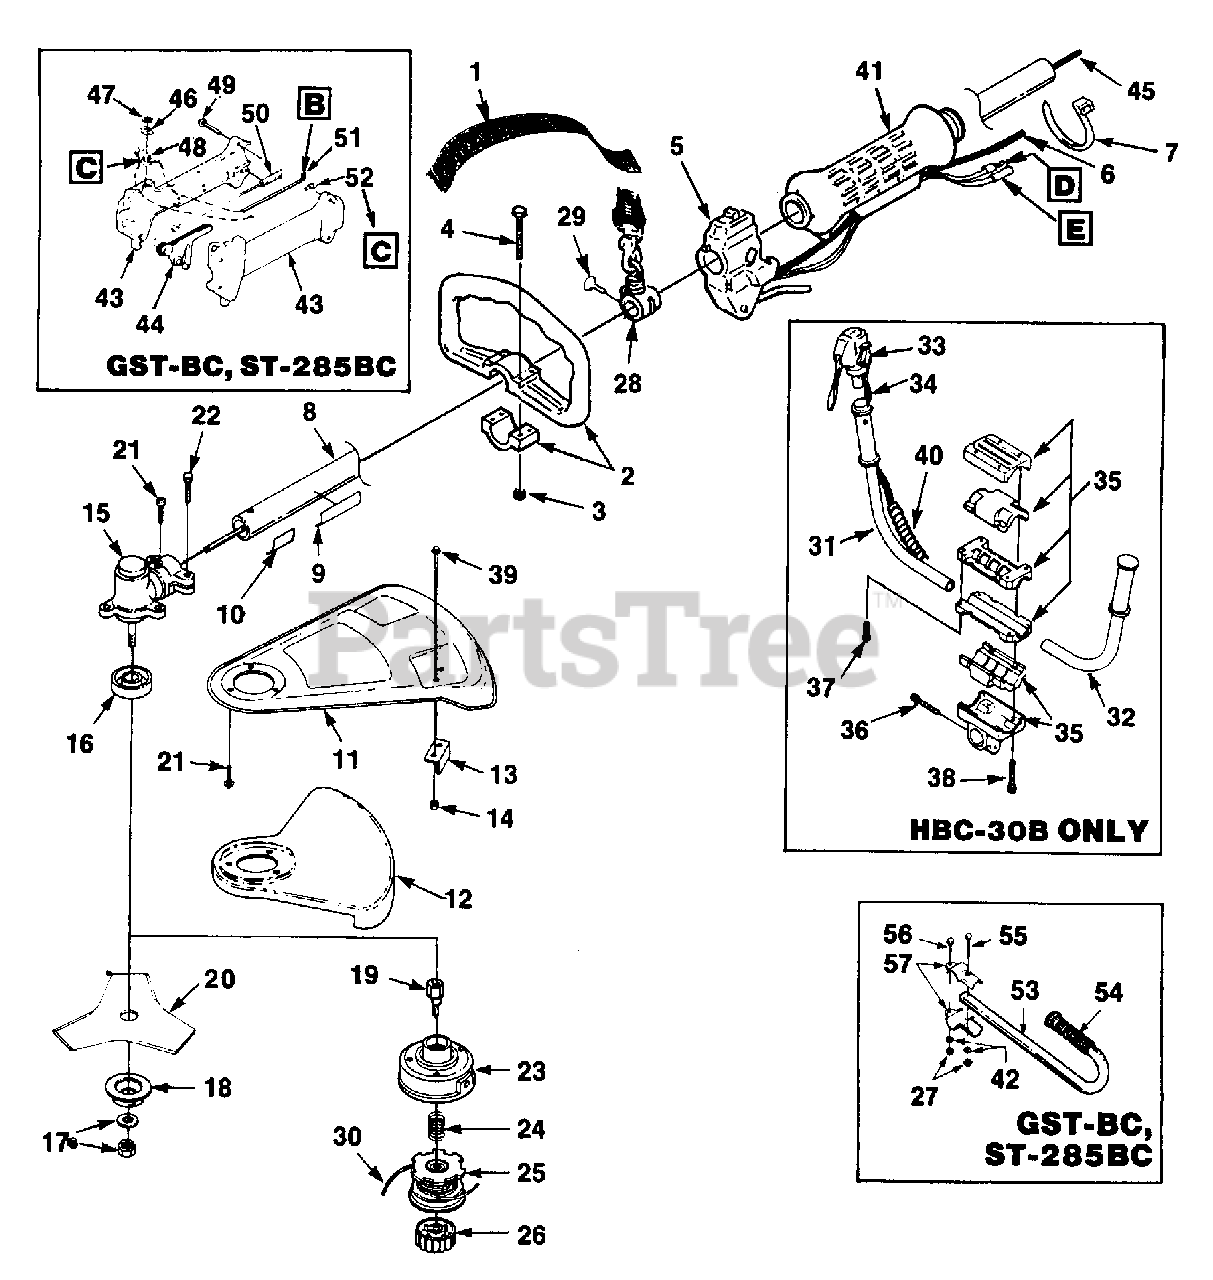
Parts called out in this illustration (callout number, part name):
1	HARNESS w/CONNECTOR
2	HANDLE (ST-385BC, HBC-30)
3	NUT (ST-385BC, HBC-30)
4	SCREW (ST-385BC, HBC-30)
5	THROTTLE & SWITCH w/Lead (ST-385BC, HBC-30)
6	THROTTLE CABLE (ST-285BC)
7	CABLE- Tie
8	HOUSING- Drive shaft (ST-385BC)
9	DECAL- Starting Instructions
10	DECAL- Warning
11	DEFLECTOR- Grass
12	GUARD- Blade (ST-285BC, ST-385BC, GST-BC, HBC-30, HBC-30B)
13	BLADE- Cut-off (ST-285BC, ST-385BC, GST-BC)
14	NUT (10-24)
15	GEAR HEAD (ST-385BC, GST-BC, HBC-30, HBC-30B)
16	WASHER- Flange
17	NUT- Hex (L.H.)
18	WASHER- Flange
19	CONNECTOR- Drive
20	TRI-ARC BLADE (ST-385BC,
21	SCREW (10-24 x 1/2")
22	SCREW (10-24 x 1")
23	HOUSING & EYELET
24	SPRING- Compression
25	SPOOL & STRING (Dual Line) (ST-275BC)
26	RETAINER- Spool
27	NUT (1/4-20)(GST-BC & ST-285BC)
28	BRACKET- Hanger
29	SCREW- Thumb (10-24 x 1/2")
30	LINE- Replacement (.095 Dia.)(1 lb. Box)(ST-385BC,GST-BC,HBC-30,HBC-30
31	HANDLE BAR (HBC-30B)
32	HANDLE BAR (HBC-30B)
33	SWITCH & LEAD (HBC-30B)
34	THROTTLE CABLE (HBC-30B)
35	HANDLE BRACKET (HBC-30B)
36	SCREW- Soc hd.
37	SCREW- Hex hd.
38	SCREW- Hex hd.
39	SCREW (10-24 x 3/8")
40	SLEEVING- Plastic (HBC-30B)
41	GRIP- Handle (ST-385BC, HBC-30, HBC-30B)
42	WASHER (1/4")(GST-BC,ST-285BC)
43	HANDLE GRIP ASSEMBLY (GST-BC, ST-285BC)
44	TRIGGER (GST-BC, ST-285BC)
45	SHAFT- Drive (ST-385BC, GST-BC, HBC-30, HBC-30B)
46	PLATE- Indicating (GST-BC, ST-285BC)
47	NUT- (GST-BC, ST-285BC)
48	SWITCH- Toggle (GST-BC, ST-285BC)
49	SCREW- Plastite (#8 x 3/4") (GST-BC, ST-285BC)
50	CABLE- Throttle (GST-BC, ST-285BC)
51	LEAD- Electrical (GST-BC, ST-285BC)
52	LEAD- Ground (GST-BC, ST-285BC)
53	HANDLE BAR ("J") (GST-BC, ST-285BC)
54	GRIP (GST-BC, ST-285BC)
55	SCREW (1/4-20 x 1 1/2") (GST-BC & ST-285BC)
56	SCREW (1/4-20 x 1") (GST-BC & ST-285BC)
57	CLAMP- Handle bar (GST-BC & ST-285BC)
